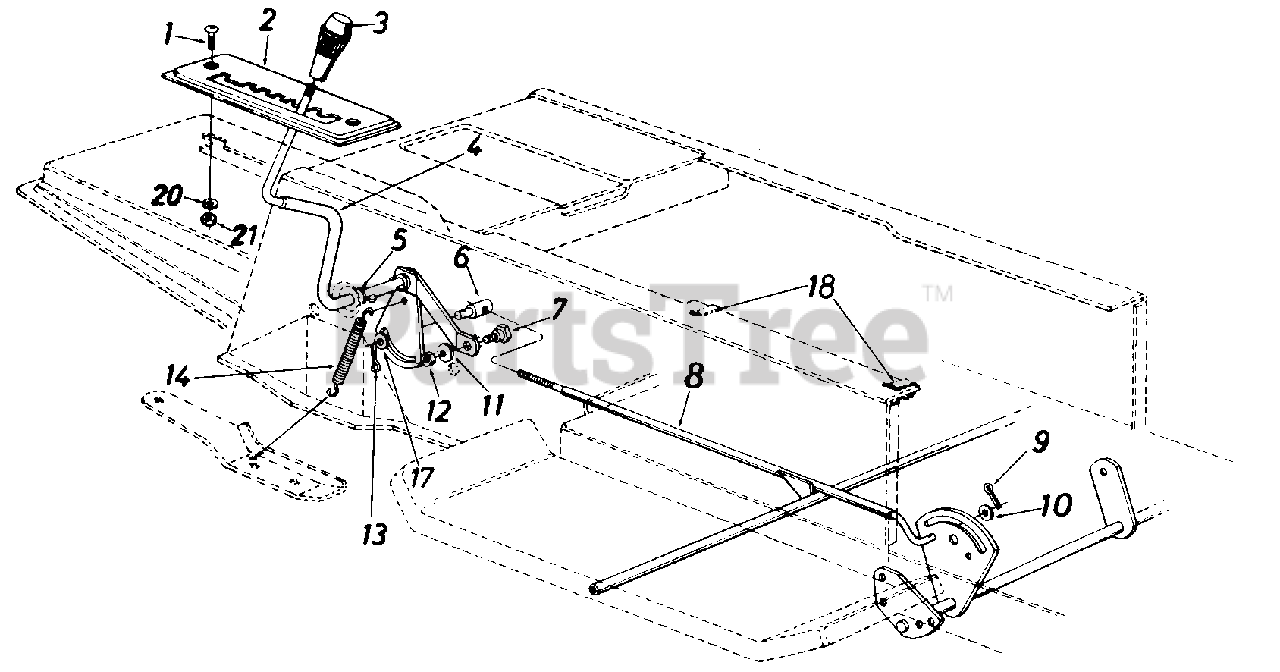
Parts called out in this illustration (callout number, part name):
1	Truss Mach. Scr. 1/4-20 x .75" Lg.
4	Speed Selector Cam Ass'y.
5	Flat Washer .53" I.D. x .93"
6	Ferrule 3/8-24 x .37" Dia.
7	Shoulder Bolt .435" Dia. x .160
8	Speed Control Rod Ass'y.
9	Cotter Pin 3/32" Dia. x .75"
10	Fl-Wash. .469" I.D. x .88"
11	L-Wash. 5/16" I.D.*
12	Hex Nut 5/16-18 Thd.
13	Cotter Pin 3/32 Dia. x .75"
14	Spring
17	Fl-Wash. .385" I.D. x .62"
20	Lock Wash. 1/4" I.D.
21	Hex Nut 1/4-20 Thd.
